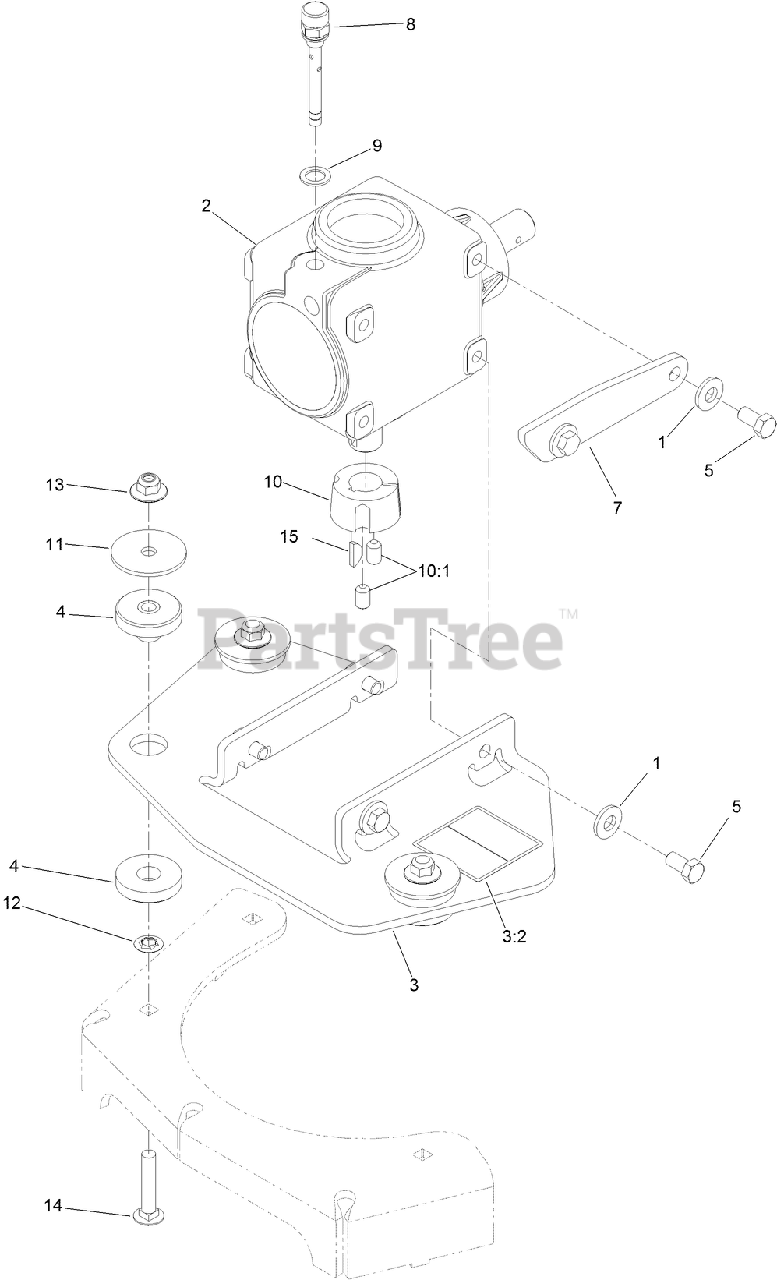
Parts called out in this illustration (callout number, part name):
1	WASHER-BELLEVILLE
2	GEARBOX ASM
3	MOUNT-GEARBOX
3:2	DECAL-HAZARD, ENTANGLEMENT
4	MOUNT-ISO
5	SCREW-HH
7	STOP-GEARBOX
8	PLUG-BREATHER
9	WASHER
10	BUSHING-TAPERLOCK
10:1	SCREW-SET
11	WASHER-FLAT
12	NUT-PUSH
13	NUT-FLANGE, NI
14	SCREW-CARR
15	KEY-WOODRUFF
